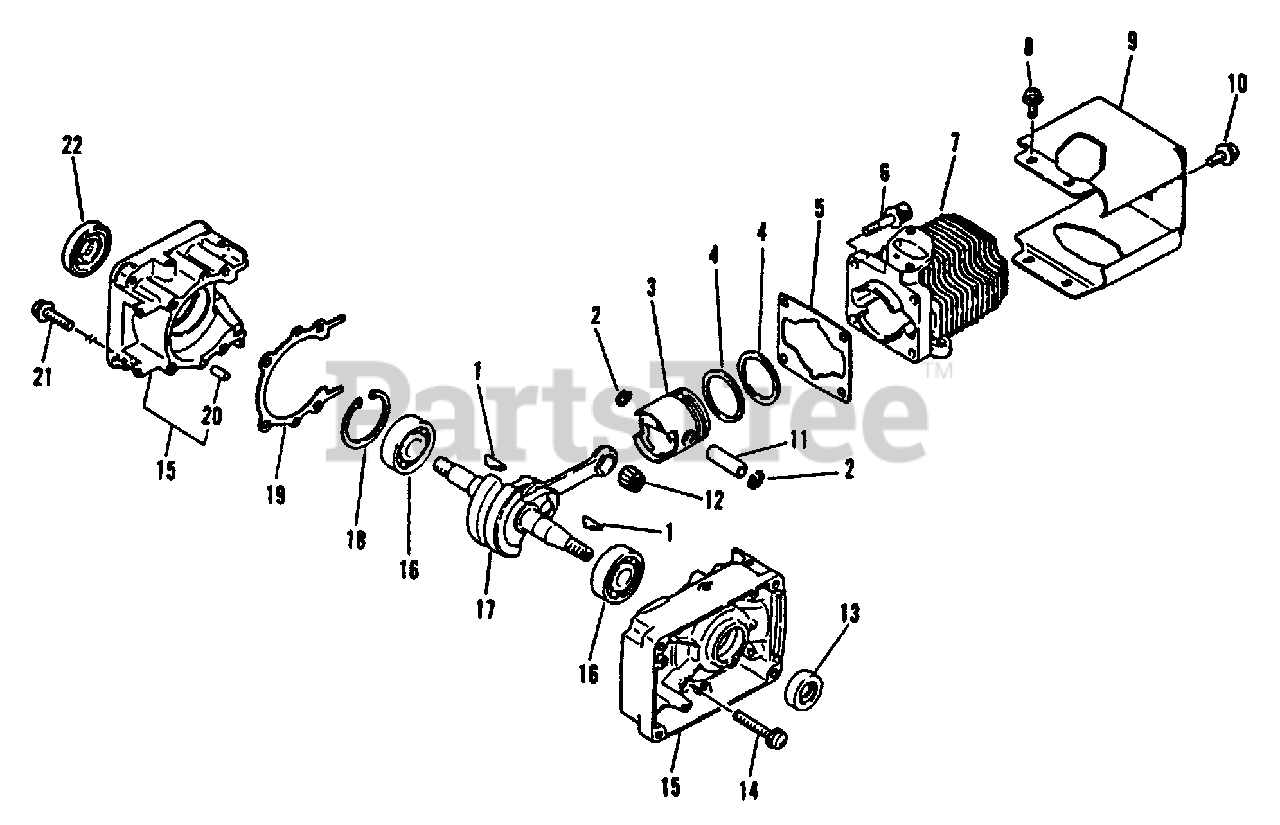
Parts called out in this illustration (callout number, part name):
1	KEY, WOODRUFF - 3×14
2	RING, SNAP
3	PISTON
4	RING, PISTON
5	GASKET, CYLINDER
6	BOLT 5×20
7	CYLINDER
8	SCREW 4×10
9	COVER, CYLINDER
10	SCREW 5×10
11	PIN, PISTON
12	BEARING, NEEDLE
13	SEAL, OIL 12
14	SCREW 5×30
15	CRANKCASE KIT
16	BEARING, BALL - 6201 C3
17	CRANKSHAFT
18	RING, SNAP Ø32
19	GASKET, CRANKCASE
20	PIN, LOCATING 4
21	SCREW 5×20
22	SEAL, OIL 12
22	GASKET KIT
